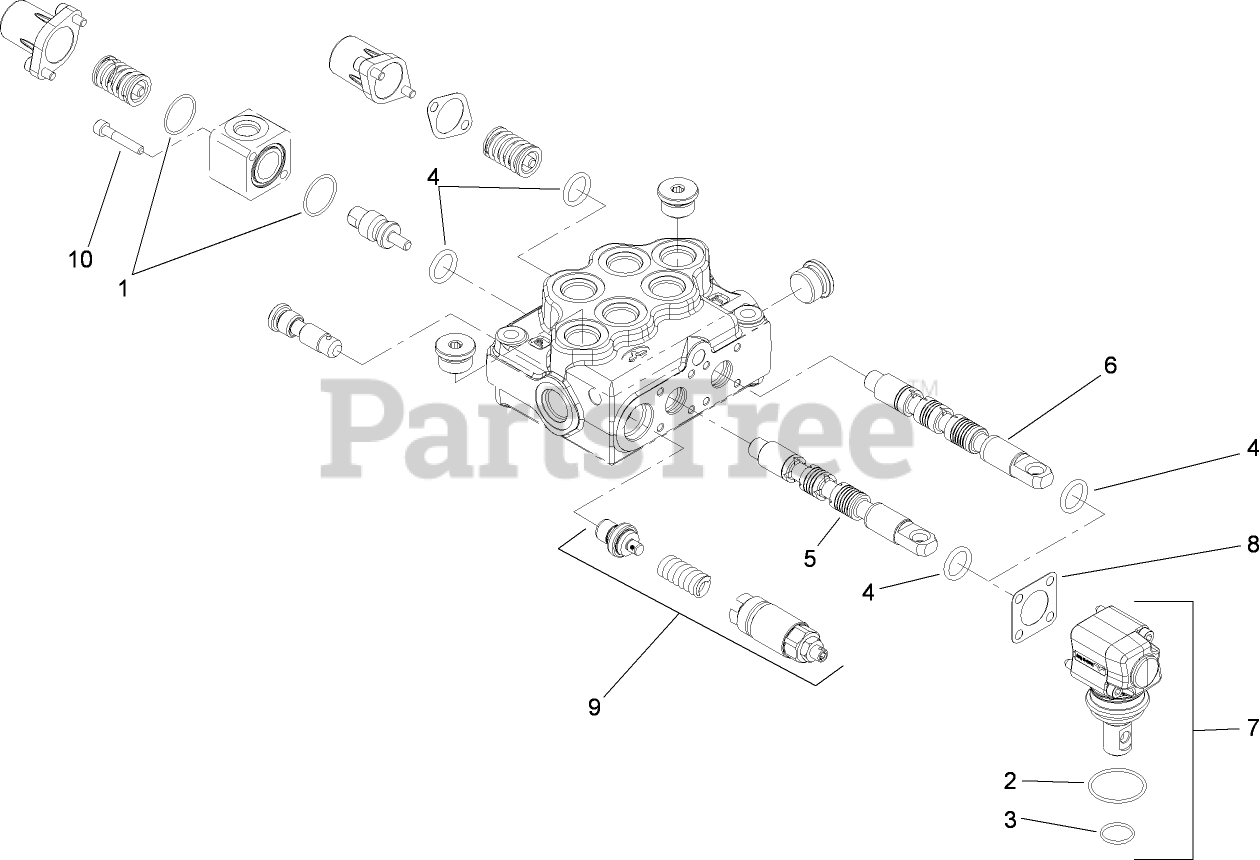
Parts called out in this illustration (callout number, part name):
1	O-RING SEAL
2	O-RING SEAL
3	O-RING SEAL
4	SEAL-VALVE
5	VALVE-SPOOL
6	VALVE-SPOOL
7	LEVER KIT
8	GASKET
9	VALVE-RELIEF
